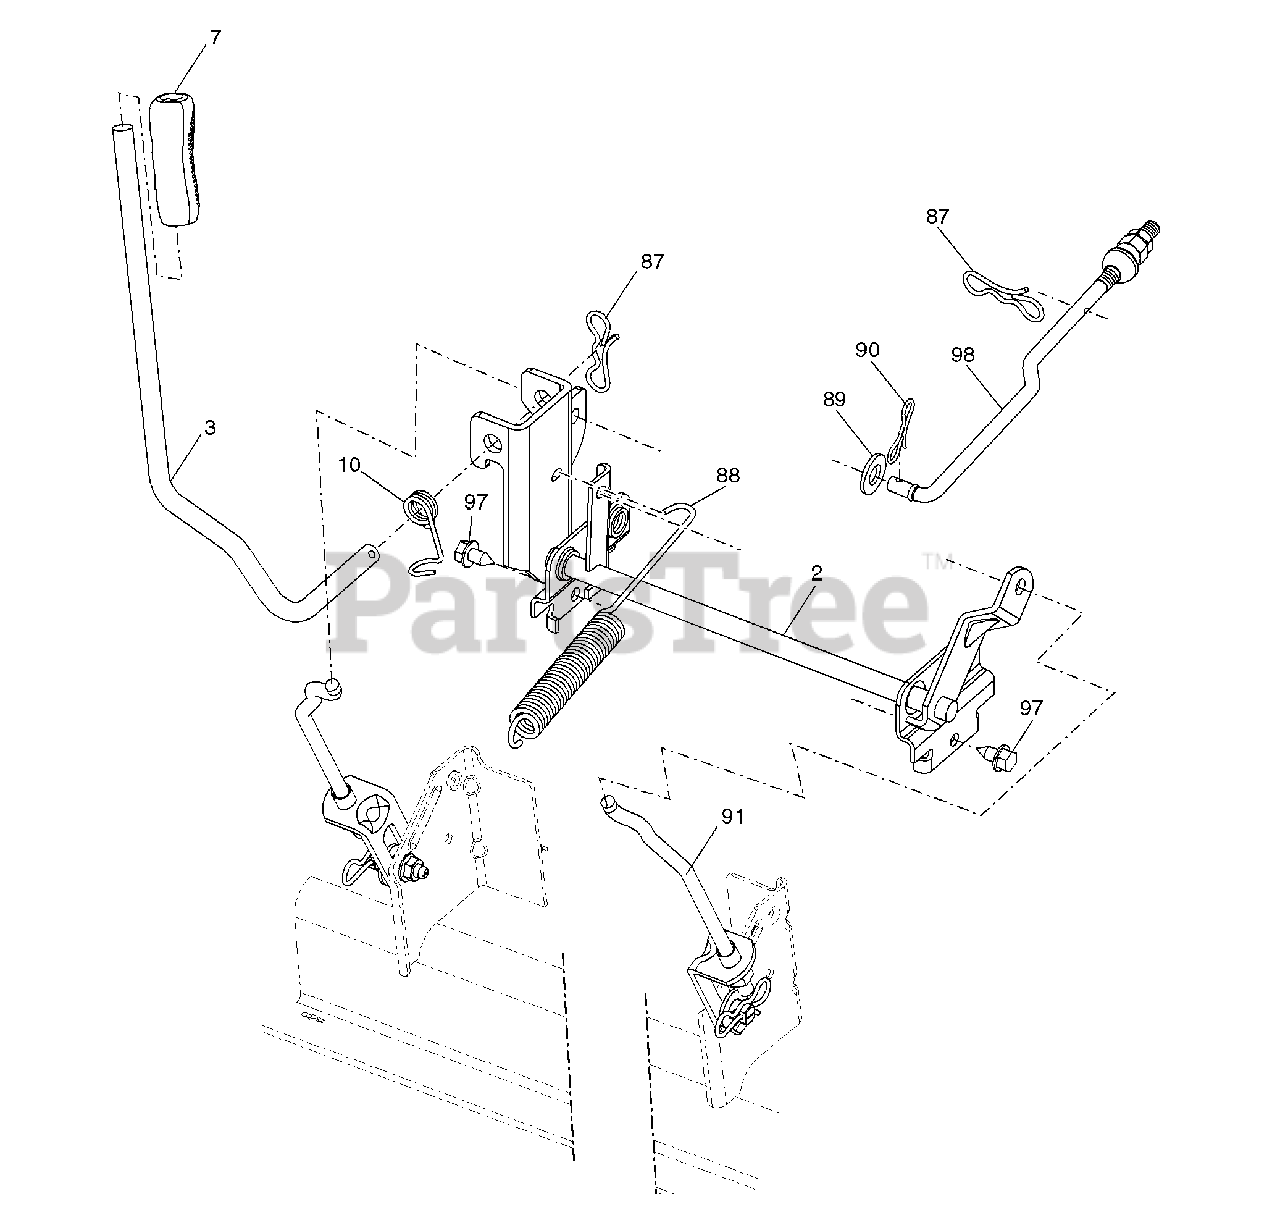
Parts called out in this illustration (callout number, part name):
2	Shaft Asm., Lift
3	Lever Asm., Lift Rh
7	Grip, Lever
10	Spring Torsion
87	Pin Cotter 7/16 Bow Tie Lock
88	Spring Lift Assist
89	Washer Clear Zinc
90	Pin Cotter 5/16 Bow Tie Lock
91	Link Lift Susp Mower Rear
97	Screw 3/8-16 x .75 Smgml Tap/R.Z
98	Link Lift Susp. Front Mower
